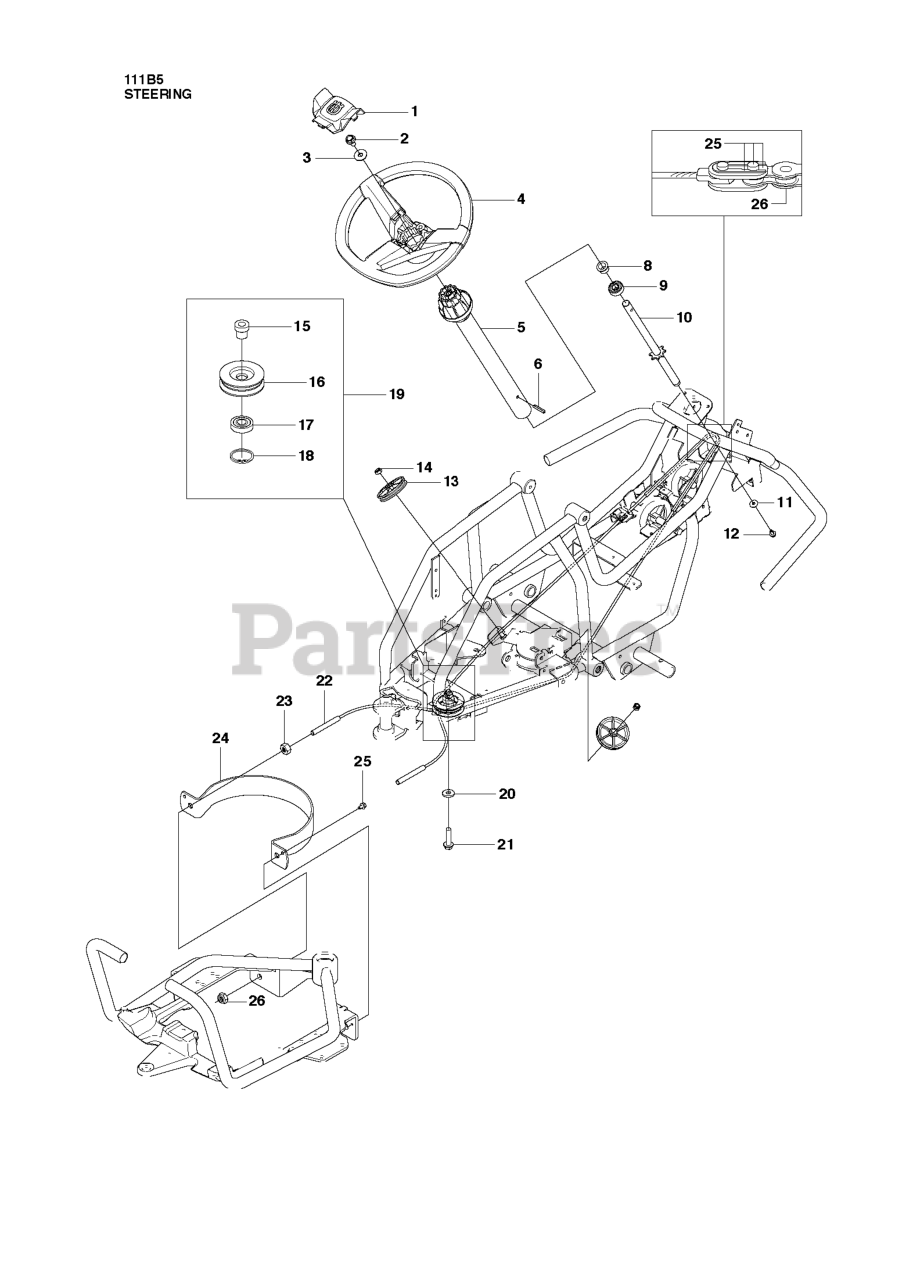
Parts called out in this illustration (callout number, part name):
1	RP INSERT.CAP.WHL.STRG.HUSQ.
4	RP WHEEL.STEER.HUSQ.PREM.OVMLD
9	BALL BEARING 6004-2RS1
11	WASHER - 26X6.5X1.6
12	SCREW EHHFM
14	LOCKNUT M6
17	BALL-BEARING 6204-2RS
18	CIRCLIP SGH 47
19	STEERING ASSY
22	RP STEERING WIRE
23	NUT
24	GUIDE RAIL
25	SCREW
26	STEERING CHAIN
26	NUT
